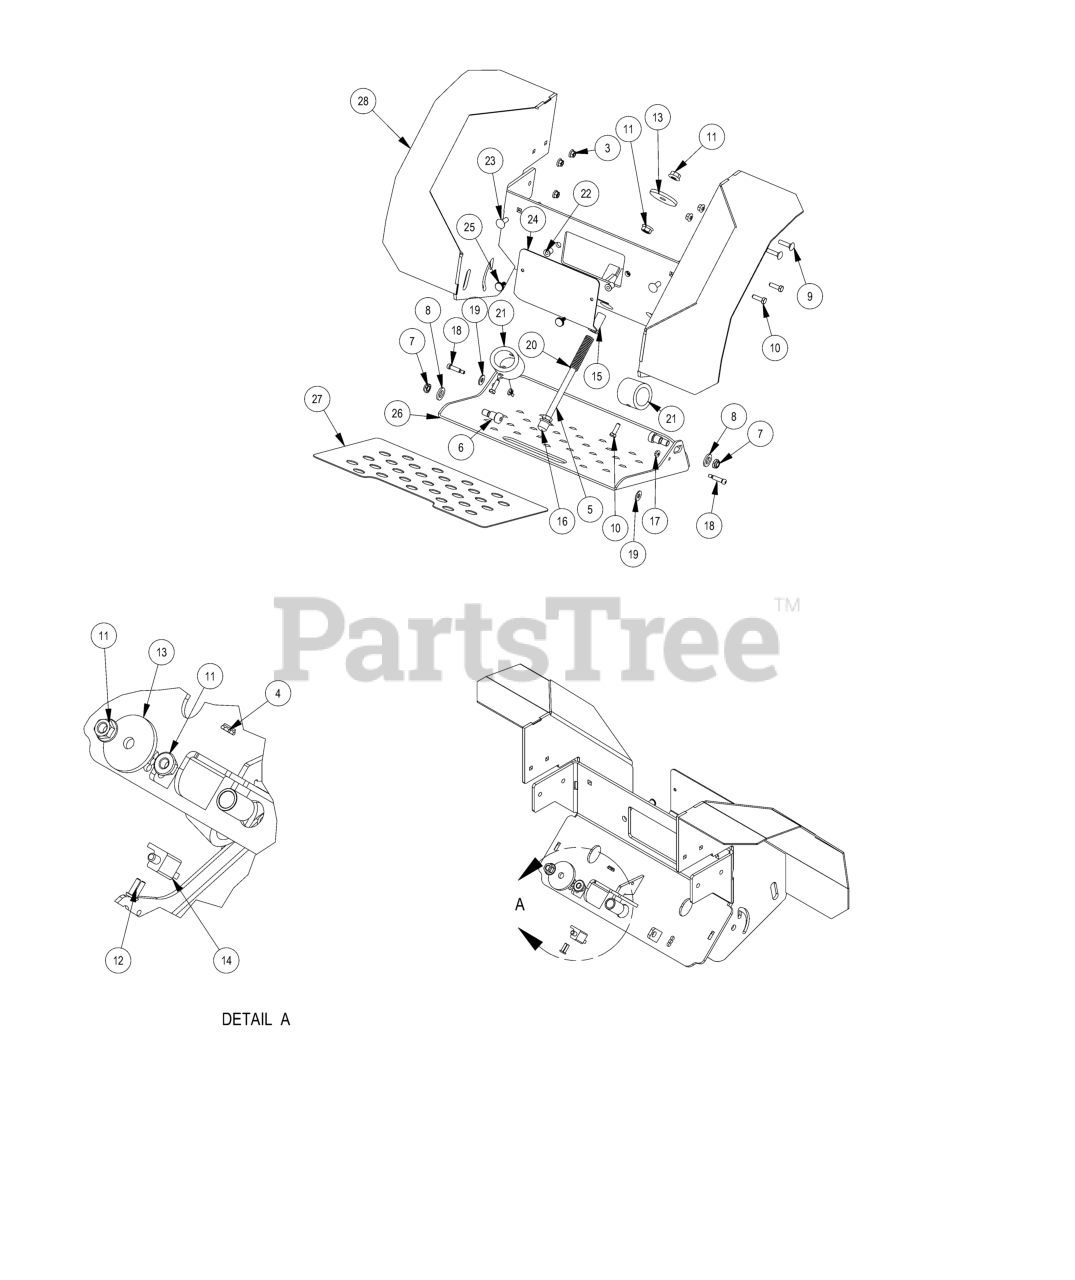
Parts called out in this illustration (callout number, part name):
1	5/16-18 HEX SERRATED FLANGE NUT HARD/ZINC
2	3/8 Nylock Flange Nut
3	5/16-18 NYLON INSERT FLANGE LOCKNUT ZINC
4	10-24 NYLON INSERT LOCKNUT ZINC
5	1/2-13 X 6 HEX CAP SCREW (GR.5) ZINC
6	5/8 X 5/8 SOCKET SHOULDER BOLT ZINC YELLOW
7	1/2-13 Nylon Insert Nut
8	.635 ID X 1.120 OD X .140 THICK FLAT WASHER NYLON
9	5/16-18 X 1-1/4 CARRIAGE BOLT ZINC
10	5/16-18 X 1 HEX CAP SCREW (GR.5) ZINC
11	1/2-13 HEX SERRATED FLANGE NUT HARD/ZINC
12	10-24 X 3/4 BUTTON SOCKET CAP SCREW 18-8 STAINLESS STEEL
13	MZ Deck Idler Spacer
14	safety Switch
15	.504 ID X .740 OD X 1.625 LGTH SLEEVE WASHER NYLON
16	Hex Nut Cap
17	1/4-20 HEX SERRATED FLANGE NUT HARD/ZINC
18	Steel Shoulder Screw 1/4"-20 x 7/8" Diameter 5/16"
19	5/16 USS FLAT WASHER (7/8 OD) ZINC
20	Rider Presence Spring 9657K145
21	2019 Revolt Platform Dampener
22	3326 Wellnut (1/4-20 x 5/18")
23	3/8-16 X 1 CARRIAGE BOLT (GR.5) ZINC
24	2019 Stand On Access Panel Plate Black Part
25	1/4"-20 x 3/4" Knurled Thumb Screw
26	2020 36" Stand-On Platform Plate-RAW
27	Grip Tape for 026-0158-00
28	2023 SD 34 Platform Support
